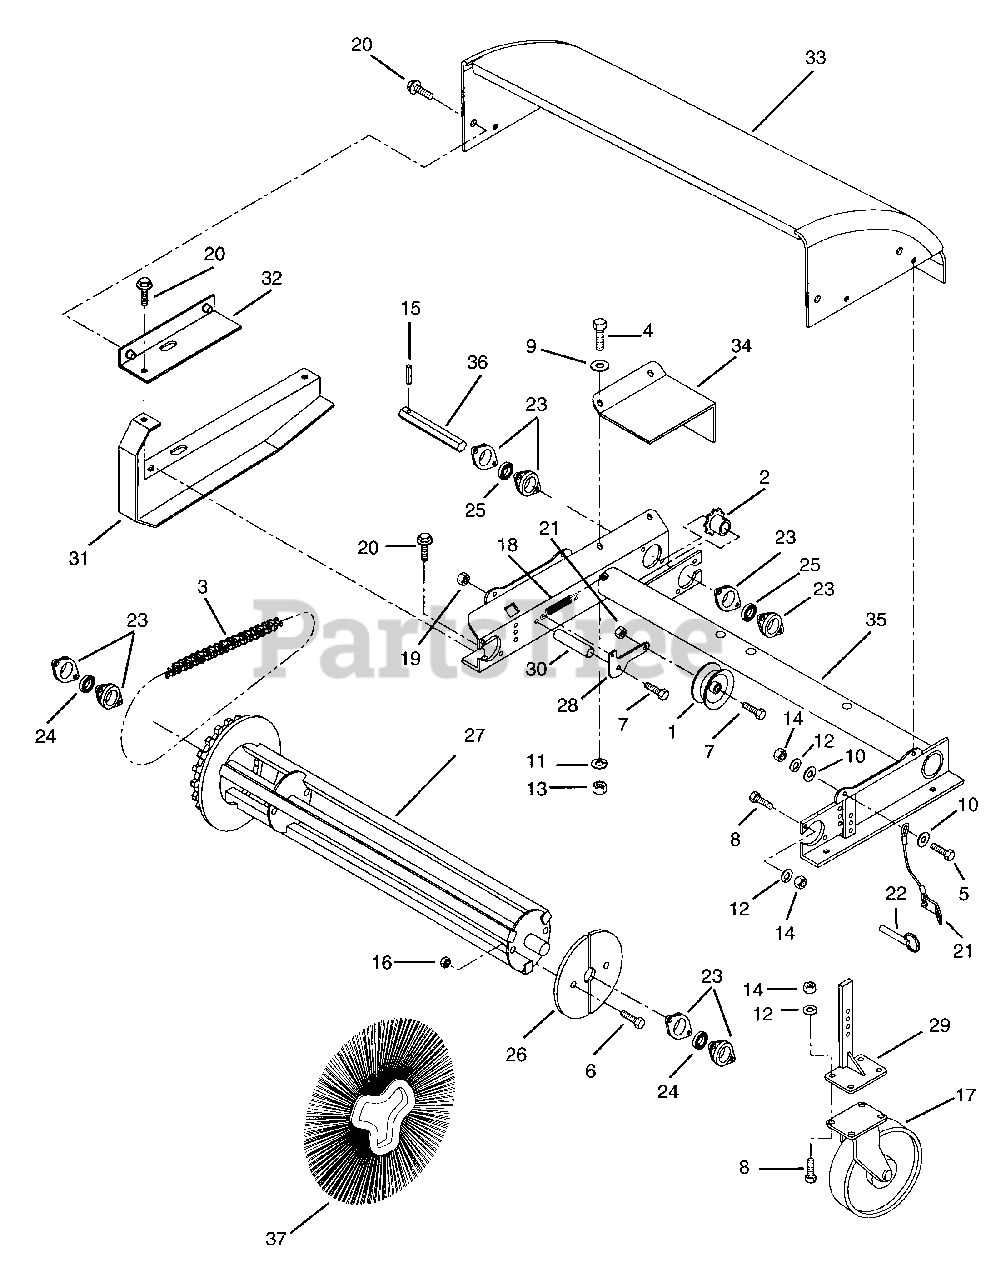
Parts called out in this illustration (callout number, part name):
1	CHAIN TIGHTENER
2	SPROCKET
3	CHAIN, ASS'Y #40X106 EDLS W/LK
4	@BLT-HEX .25-20X.75 GR5 YWZC
5	@BLT-HEX .31-18X1.00 GR5 YWZC
6	@BLT-HEX .31-18X2.25 GR5 YWZC
7	@BLT-HEX .38-16X1.50 GR5 YWZC
8	@BLT-HEX .31-18X.75 GR5 YWZC
9	@WSHR-FL-STL.281X.62X.065 YWZC
10	@WSHR-FL-STL.312X.734X.065 YWZ
11	@WSHR-LK .25X.062 REG YWZC
12	@WSHR-LK .31X.078 REG YWZC
13	@NUT-HEX .25-20 YWZC
14	@NUT-HEX .31-18 YWZC
15	PIN, SPRING LOK .187 X 1.25
16	NUT, LOK STAMPED .312-18 TINN.
17	WHL, 5 DIA.
18	SPRING, TENSION .50 X 3.0
19	@NUT-LK-CTR .38-16 YWZC
20	SCREW, GR 10.9 M6X1-20
21	LANYARD,.06 CAB.1.25X6,TYP C
22	PIN, HITCH, .38 X 2
23	FLANGE, SPHERICAL 2"
24	BRG 1.00 BORE, SPHER. OD.
25	BRG-BALL .884HEXX52MMX1.07
26	RETAINER PLATE (SET OF 2)
27	WELD, CORE C36TW
28	ARM, IDLER,BRM C36TW
29	WELD, CASTER LEG, C36TW
30	BSHG, .62X12 GA X.75
31	SHIELD,CHAIN, ARIENS
32	SHIELD, CHAIN,TOP,ARIENS
33	KIT, HD, ARIENS
34	SHIELD, INPUT, ARIENS
35	WELD, BFRM,ARIENS
36	SHAFT, HEX 20.5, W/HOLE
37	SET,SECTION,24",P,CONV.
